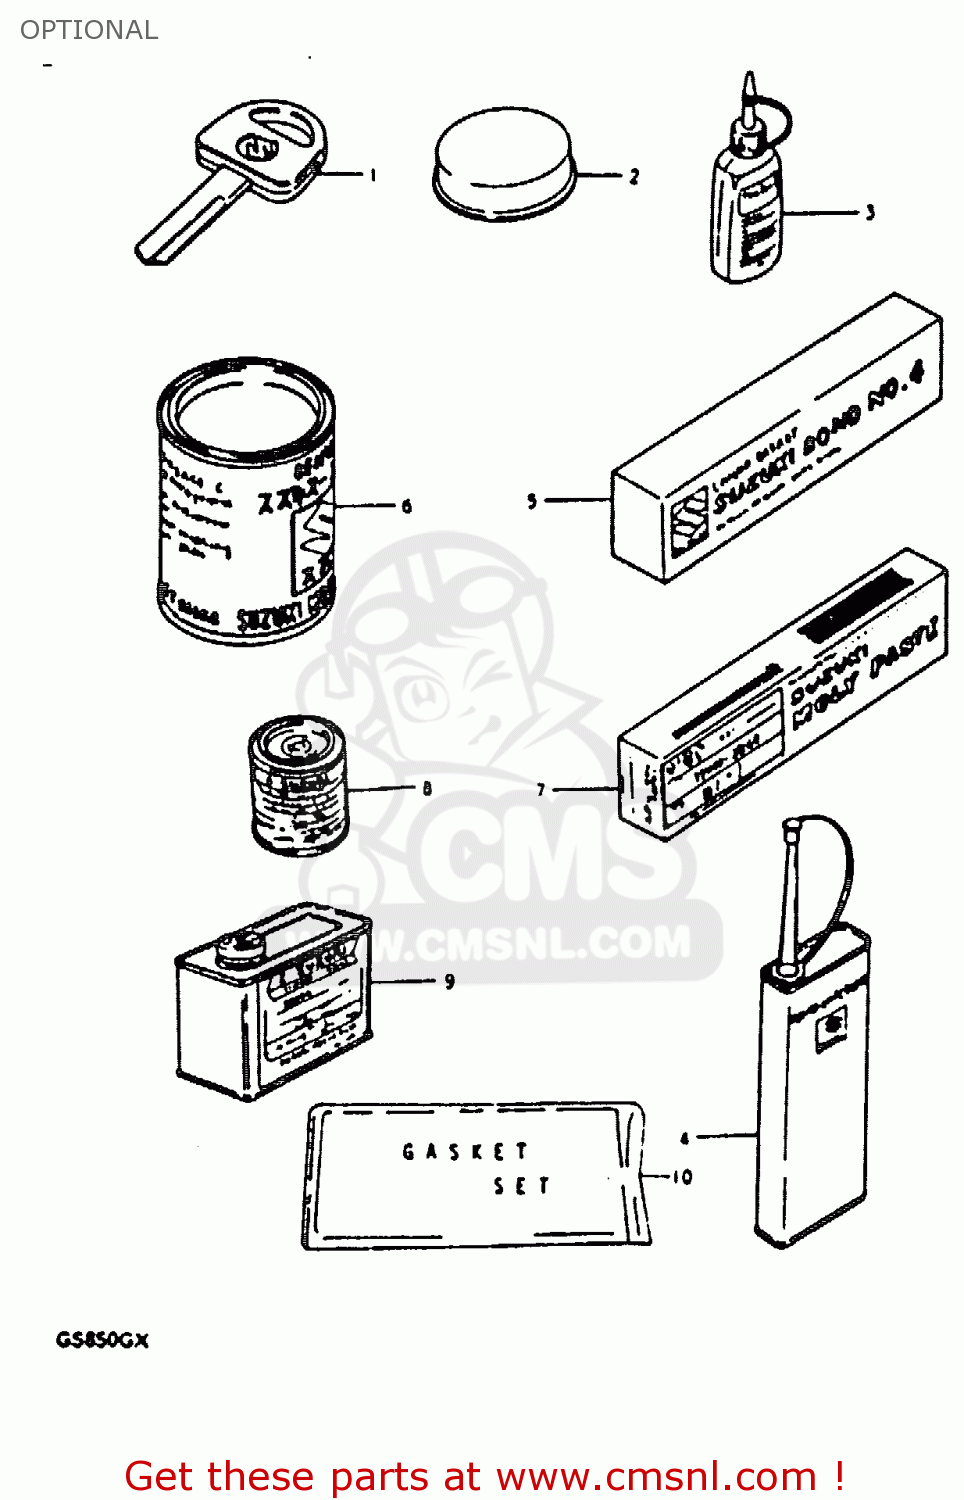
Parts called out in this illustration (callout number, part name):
1	KEY,BLANK
2	GREASE,PBC FOR BRK PAD 20G
3	THREAD LOCK SUPER (1332B)
4	THREAD LOCK NO.1401 CLEAR 200G
5	BOND 1104
6	GREASE(C)EP2 LITHIUM 150G
7	SUZUKI MOLY PASTE
8	PAINT,BLACK
9	PAINT (BLACK)
10	GASKET SET
